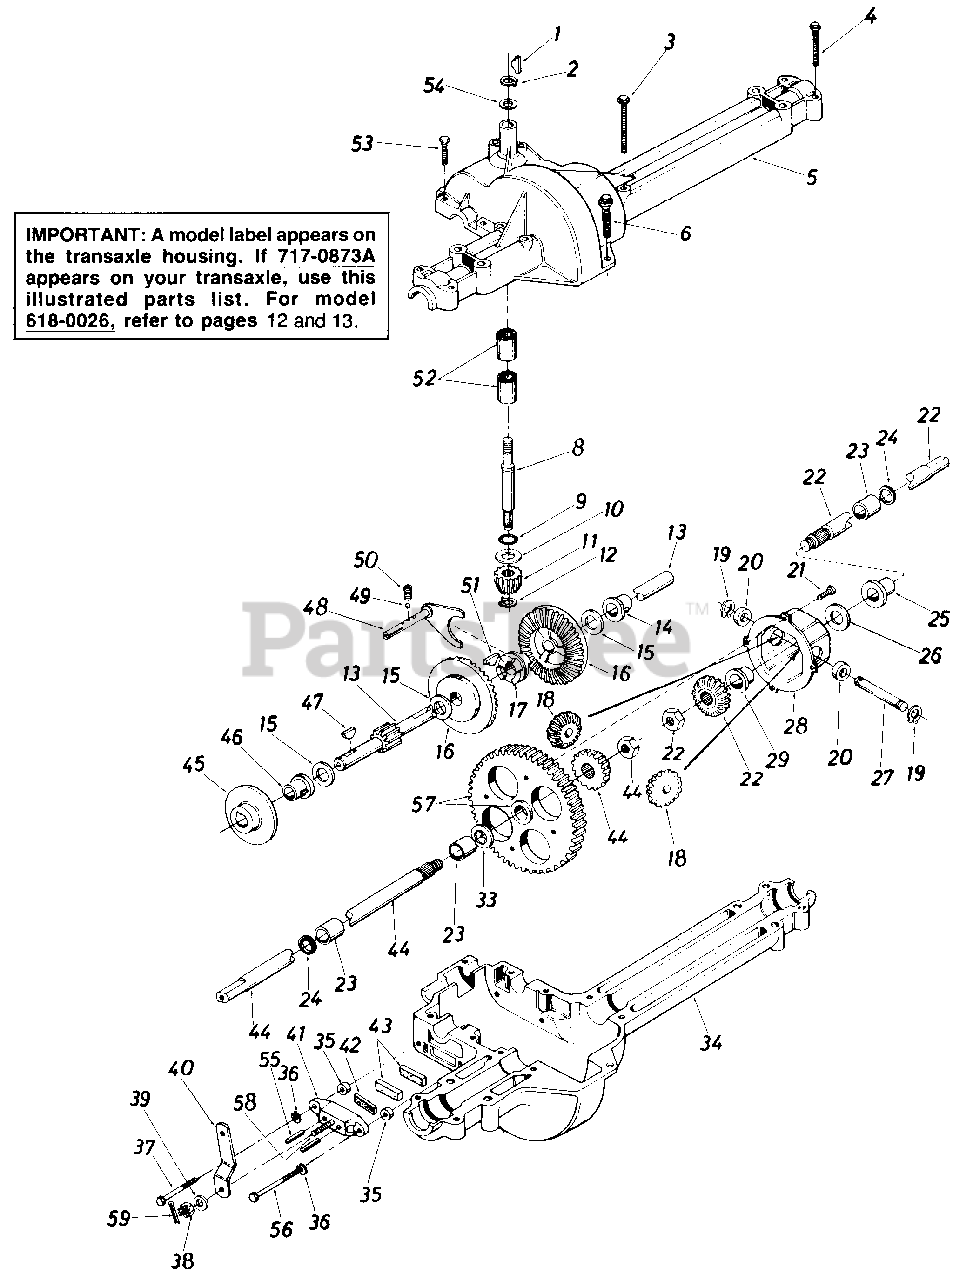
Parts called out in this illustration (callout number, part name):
1	#4 Hi-Pro Key 3/32 x 5/8" Dia.
2	Snap Ring .625" Shaft
3	Hex Bolt 1/4-20 X 1.75" Lg.
4	Hex Tap Scr. 1/4-20 x 1.25" Lg.
5	Upper Housing
6	Hex TT-Tap Scr. 1/4-20 X .75" Lg.
9	Square Seal 518" I.D.
10	Thrust Washer 518" I.D. x 1 25" OD
11	Pinion Input 14T
12	Retaining Ring 7/16" Ext.
14	Flange Brg. 5/8" I.D. x 3/4" Lg.
15	Fl-Wash.
16	Bevel Gear 42T
17	Clutch Collar
18	Miter Gear 15T (H .D.)
19	Retainer Ring
20	Thrust Bearing
21	Pan Head Scr. 1/4-20 X .50" Lg. w/Patch
22	Axle R.H. Ass'y.-Kit
23	Sleeve Bearing 3/4" I.D. x 1.0" Lg.
24	Oil Seal 3/4" I.D.
25	Flange Bearing 3/4" I.D. x 15/1 6" Lg.
26	Fl-Wash. .760" I.D. x 1.5" O.D.
28	Differential Housing Ass'y.
33	Fl-Wash. .760" I.D. x 1.5" O.D.
34	Lower Housing
35	Spacer .53" O.D. x 3/8" Lg.
36	L-Wash. 1/4" I.D.
37	Hex Bolt 1/4-20 x 1.50" Lg. (Grade 5)
38	Castle Nut 5/16-24 Thd.
39	Fl-Wash. .344" I.D. x .875" O.D.
40	Actuating Arm
42	Puck Plate
43	Brake Puck
44	Axle L.H. Ass'y.-Kit
46	Flange Bearing 5/8" I.D. x 15/16" Lg.
47	Woodruff Key 3/16 x 5/8 HT
48	Shift Fork Ass'y.
49	Ball Detent .250" Dia.
50	Spring Detent
51	#9 Hi-Pro Key 3/16" x 3/4" Dia. HT
52	Needle Brg. 5/8" I.D. x 1/2"
53	Hex Bolt 1/4-20 x 1.00" Lg.
54	Fl-Wash. 5/8" I.D. x .030
55	Actuating Pin 5/16" Dia.
56	Hex Bolt 1/4-20 x 2.50" Lg. (Grade 5)
57	Differential Gear 72T Ass'y. w/Bearing
58	Sq. Hd. Bolt 5/16-24 Thd.
59	Cotter Pin 3/32" Dia. x 1 Lg
